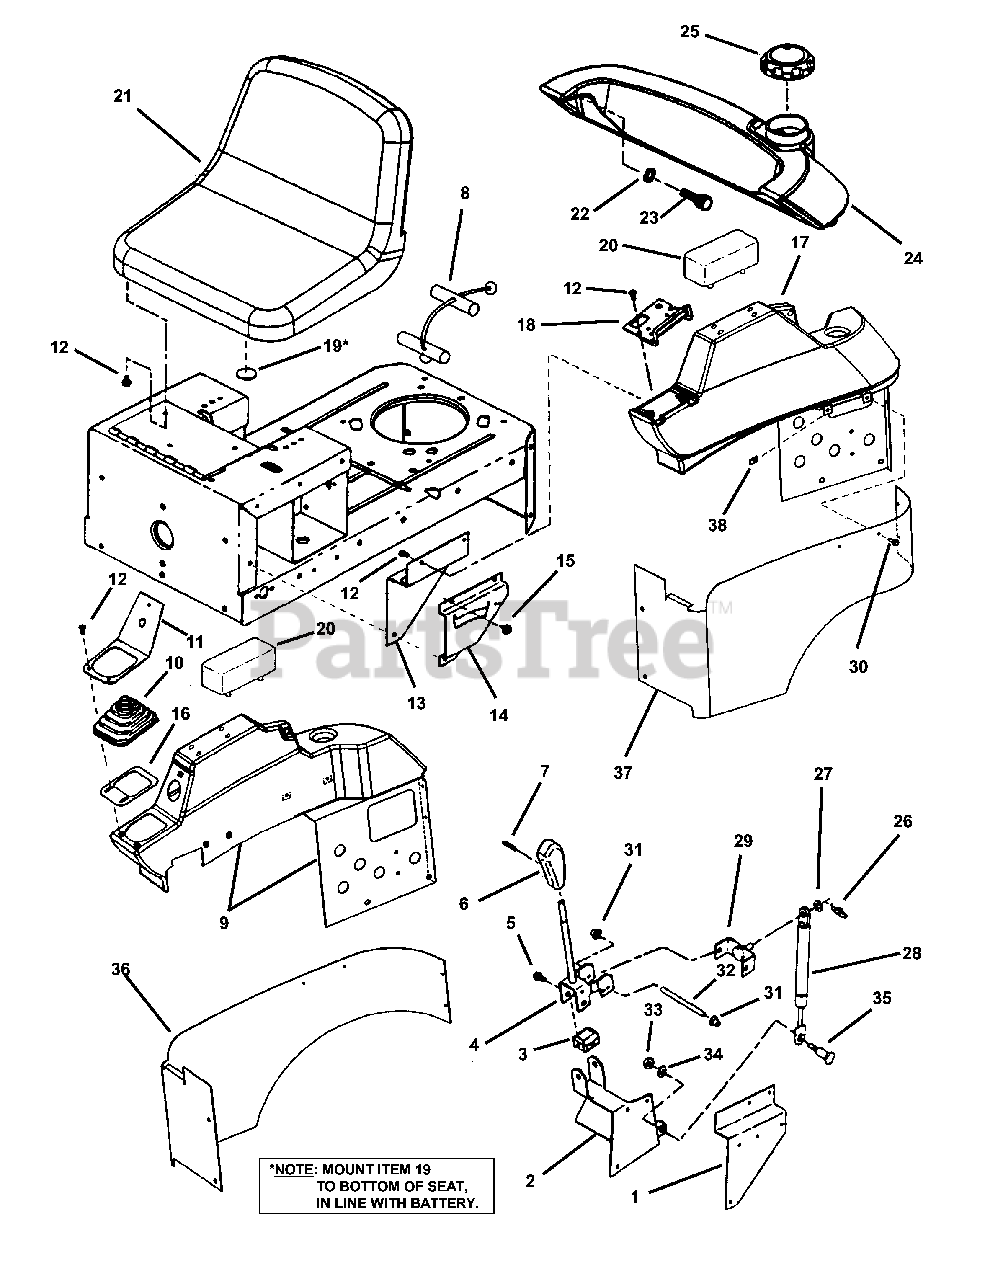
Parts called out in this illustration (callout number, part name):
1	BRACKET, Right Hand Tank Support
2	BRACKET, Joystick
3	PIVOT, Joystick Control
4	HANDLE, Joystick Control
5	BOLT, 5/16-18 x 3/4" Shoulder
6	LEVER, Shift Handle
7	PIN, 3/16 x 3/4" Roll
8	TETHER, Seat
9	ASSEMBLY, R.H. Fender
10	BOOT, Joystick, Rubber
11	BRACKET, Joystick/Key
12	SCREW, 1/4 x 5/8" Pan Head Self-Tapping
13	BRACKET, Left Hand Tank Support
14	BRACKET, Brake/Clutch Detent
15	SCREW, 1/4-20 x 5/8" Self-Tapping
16	SPEED PLATE
17	ASSEMBLY, L.H. Fender
18	GUARD, Throttle Control
19	BUMPER, Battery
20	ARM REST,
21	SEAT
22	WASHER, 1/4" Internal/External Tooth
23	SCREW, 1/4-20 x 1-1/2" Thumb
24	ASSEMBLY, Fuel Tank
25	CAP, Fuel Tank
26	COTTER-PIN, 3/8 Self Locking
27	WASHER, 11/32 x 11/16" Flat
28	CYLINDER, Joystick Control
29	BRACKET, Joystick Control
30	SCREW, #10-24 x 1/2" Machine
31	PUSH-NUT, 1/4"
32	PIN, Joystick
33	NUT, 5/16-18 Hex, Grade 5
34	WASHER, 21/64 Split Lock
35	BOLT, 5/16-18 Shoulder
36	FENDER, R.H. Steel
37	FENDER, L.H. Steel
38	U-CLIP, #10-24
